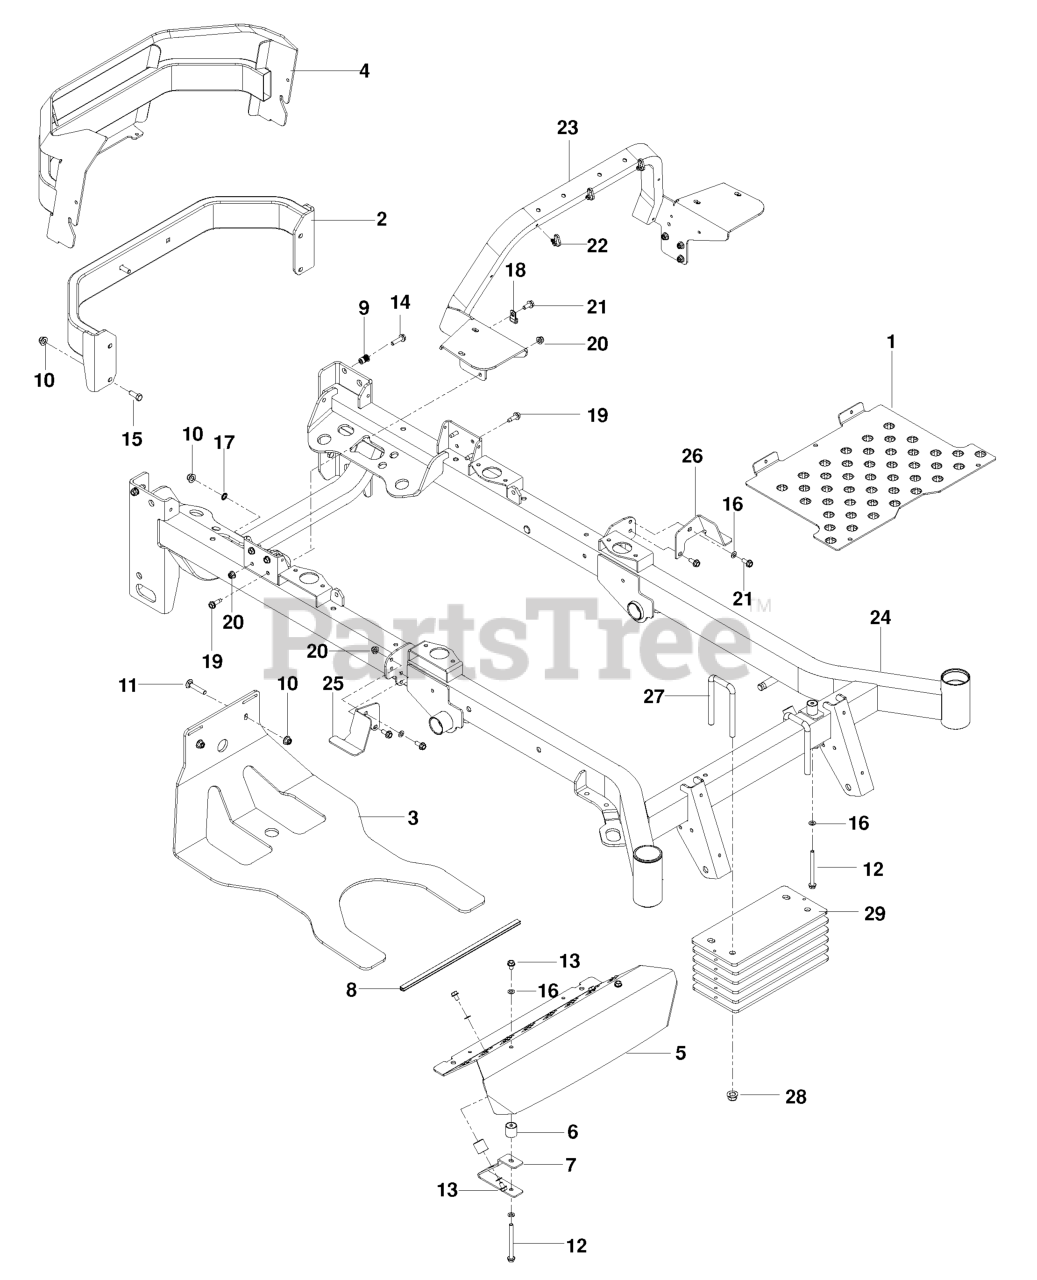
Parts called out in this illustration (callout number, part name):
1	PLATE, FLOOR PAN, OR
2	BUMPER.REAR.W/DECALS
3	PLATE, SKID, BLACK
4	GUARD, REAR W/DECALS
5	PLATE, FOOT REST, OR
6	MOUNT, F/F INSERT
7	BRACKET, REST MOUNT
8	RP.FLEX TRIM, BLK-LENGTH 1 FT
9	NUTSERT 5/16-18 THICK GRIP
10	NUT 3/8-16 HEX FLG NYLOC ZD
11	RHSNB 3/8C X 2
12	HHFS 5/16-18 X 3 3/4
13	SCR 5/16-18 X 1/2 SELFTAP ZN
14	HHFS 5/16-18 X 1.25 TPBLT GD 5
15	HCS 3/8-16X1.GRD.5.ZD
16	WASH 5/16 DISC SPRING ZD
17	WASHER 3/8 EXT STAR ZD
18	DOUBLE TUBE CLAMP
19	RP BLT 5/16-18 X 1 THRD FORM D
20	5/16-18 NYLOC FLANGE NUT
21	HHFS 5/16-18 X 3/4
22	TIE WRAP, 8-3/8", W/CLIP
23	CROSS MEMBER, GRAY
24	FRAME.DIESEL.ORANGE
25	MOUNT, TANK, RT
26	MOUNT, TANK, LT
27	LINKAGE, U-BOLT
28	NUT, 1/2-13 HEX FLG NYLOC ZD
29	PLATE, WEIGHT BLK
